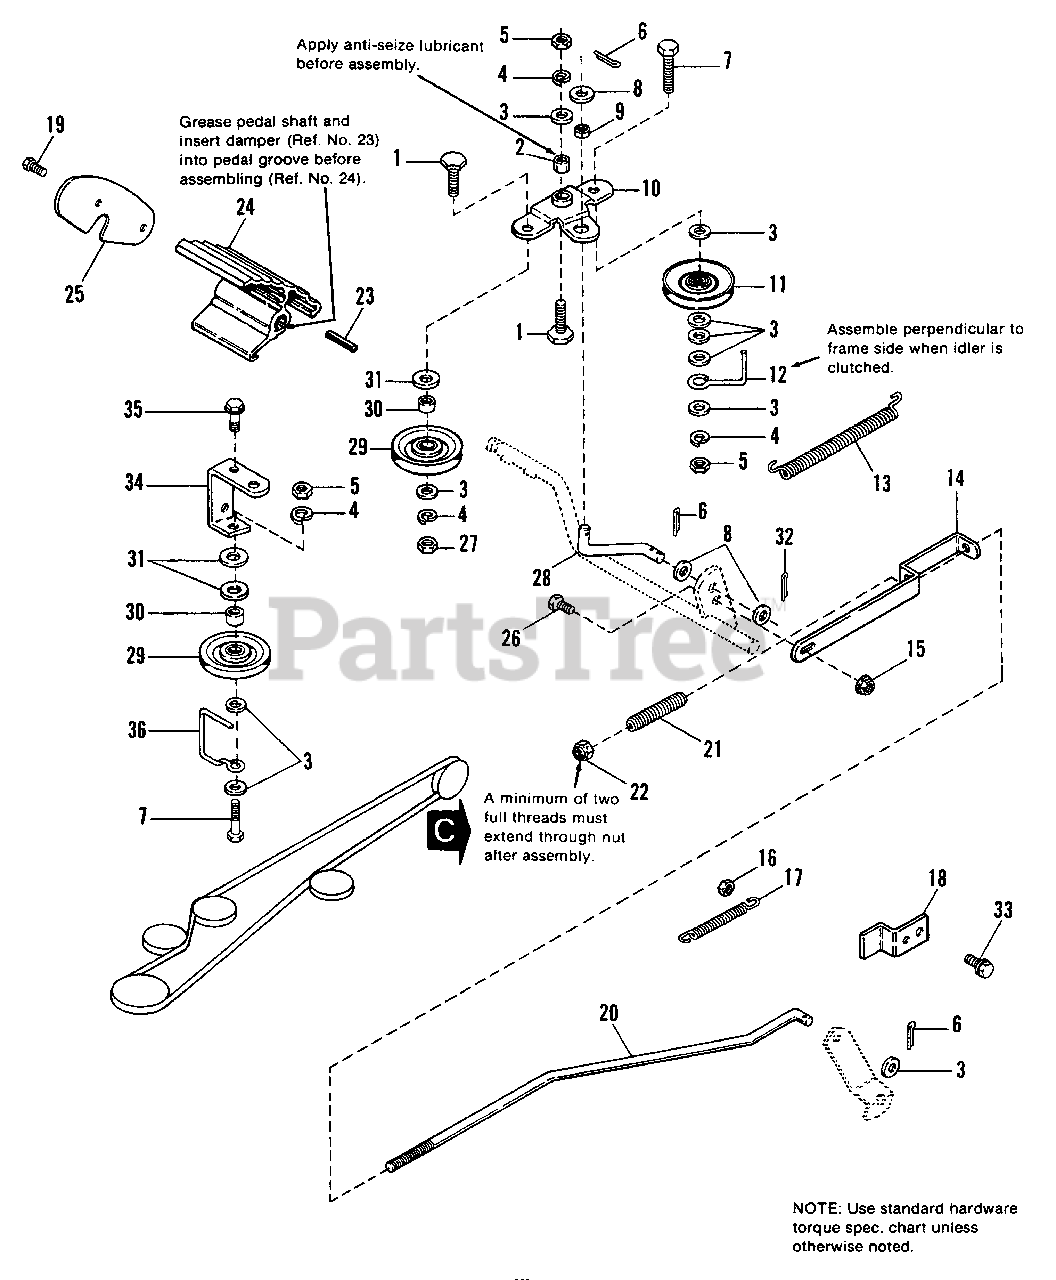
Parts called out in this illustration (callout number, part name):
1	SCREW, Hex, 3/8-16 x 1-1/4, Thin Hd.
3	WASHER, Plain, 5/16
4	LOCKWASHER, 3/8
5	NUT, Hex, 3/8-16
6	PIN, Cotter
7	CAPSCREW, Hex Hd., 3/8-16 x 1-3/4
8	WASHER, Plain, 13/32 x 7/8, 14 Ga.
9	BUSHING, Ball
10	ARM ASSY., Clutch (Mfg. No. 1690846 & 1690912)
10	CLUTCH ARM & LINK KIT (Includes Ref. No. 28)(Mfg. No. 1690759)
11	PULLEY, Idler
13	SPRING, Tension, Clutch
15	NUT, Hex, Flange Lock, 3/8-16
16	NUT, Jam Lock, 3/8-16
17	SPRING, Brake Return
18	STOP, Brake Lever
19	SCREW, Taptite, 1/4-20 x 5/8
20	ROD, Brake
22	NUT, Hex Lock, 5/16-18
23	DAMPER, Rubber
24	PEDAL, Foot
25	PLATE, End
26	CAPSCREW, Hex, 3/8-16 x 3/4
27	NUT, Hex, Jam, 3/8-16
28	LINK, Clutch Arm (Mfg. No. 1690846 & 1690912)
28	CLUTCH ARM & LINK KIT (Includes Ref. No. 10)(Mfg. No. 1690759)
29	PULLEY ASSY.
31	WASHER, 13/32 x 1, 10 Ga. Plain
32	PIN, Cotter
33	SCREW, Taptite, 1/4-20 x 1/2
34	BRACKET, Idler
35	SCREW, Taptite, 5/16-18 x 5/8
